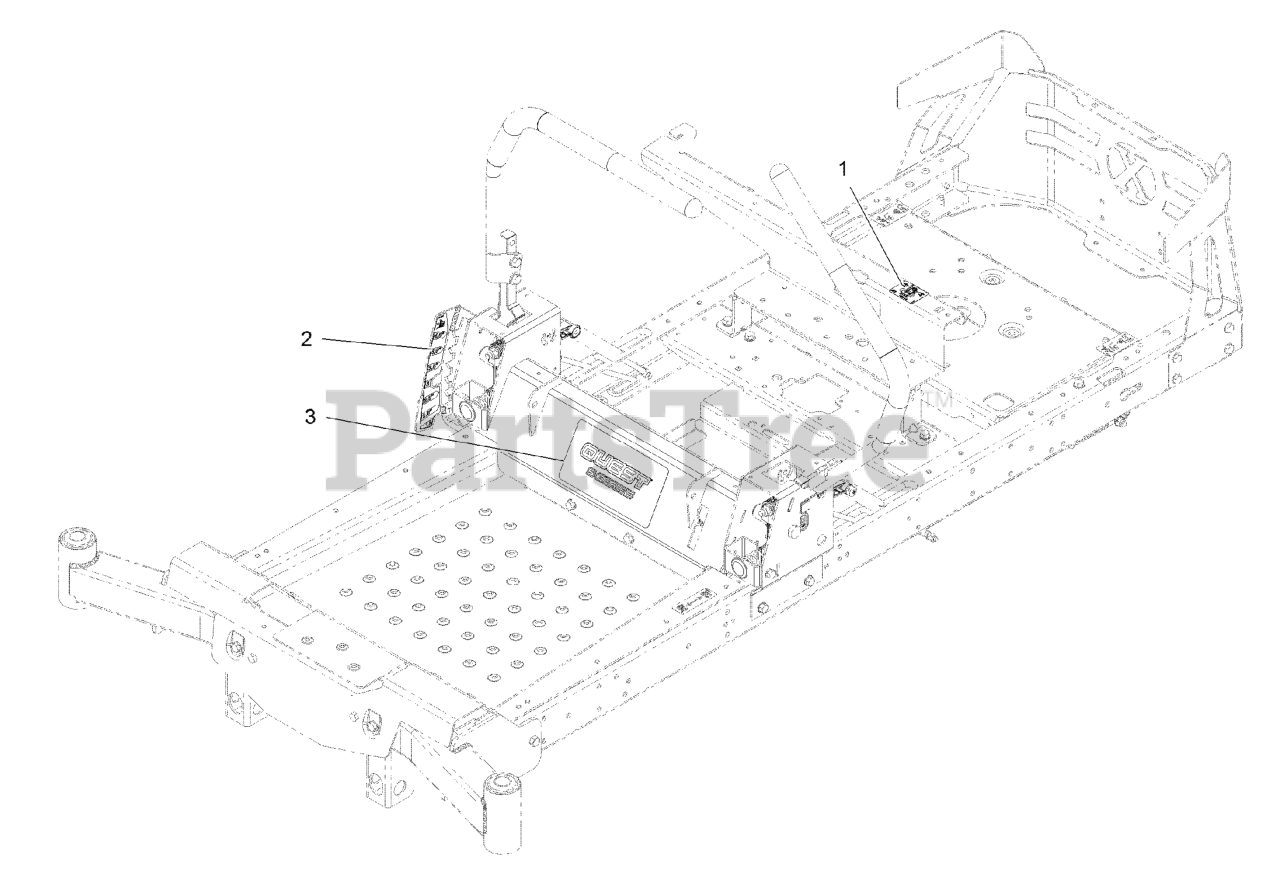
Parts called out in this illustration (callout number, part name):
1	DECAL-MAINTENANCE
2	DECAL-HOC
3	DECAL, QUEST S SERIES
